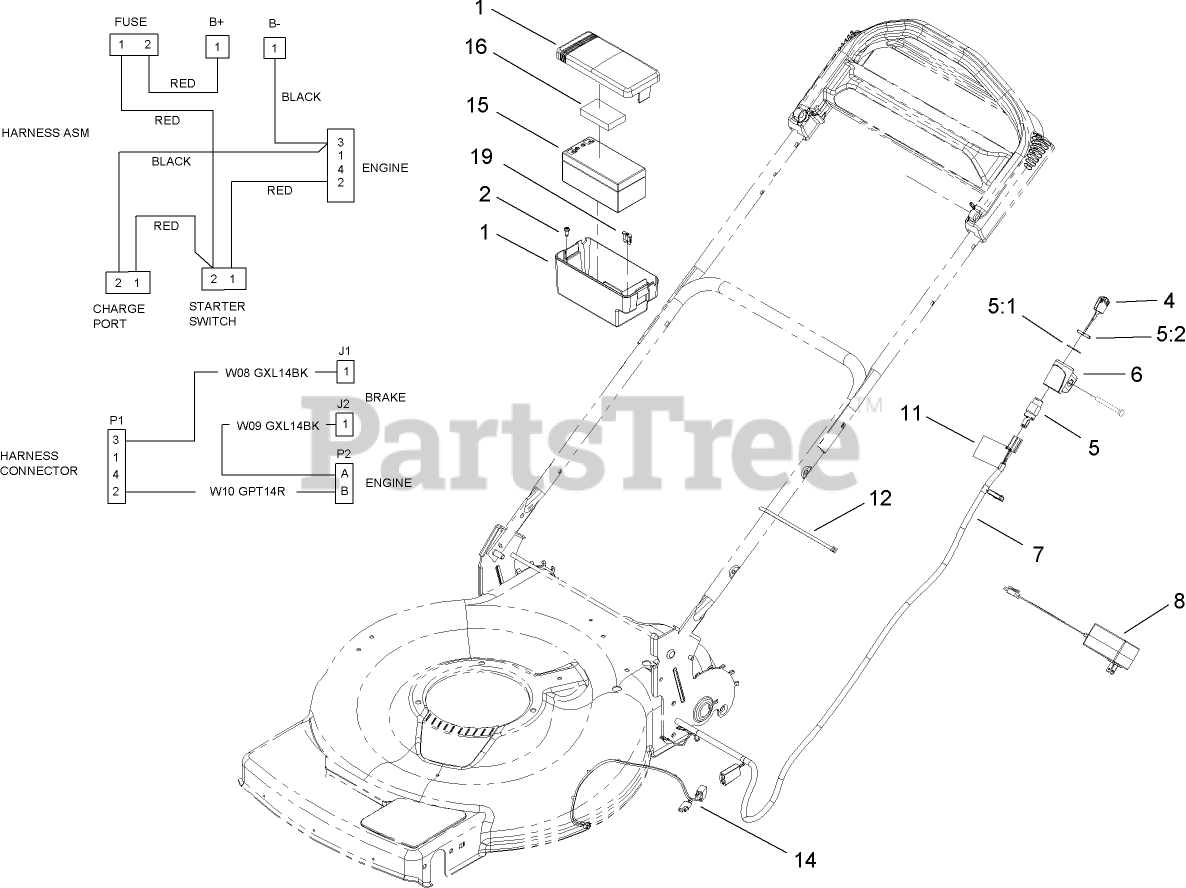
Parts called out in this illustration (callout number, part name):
1	BATTERY BOX ASM
2	SCREW-FORMING, THREAD
5	STARTER SWITCH ASM
5:1	WASHER-LOCK
5:2	NUT-HH
6	MOUNT-SWITCH
7	HARNESS-WIRE
11	DECAL-WARNING
12	TIE-CABLE
15	BATTERY-WET
16	FOAM-BATTERY, TOP
19	FUSE-40 AMP
